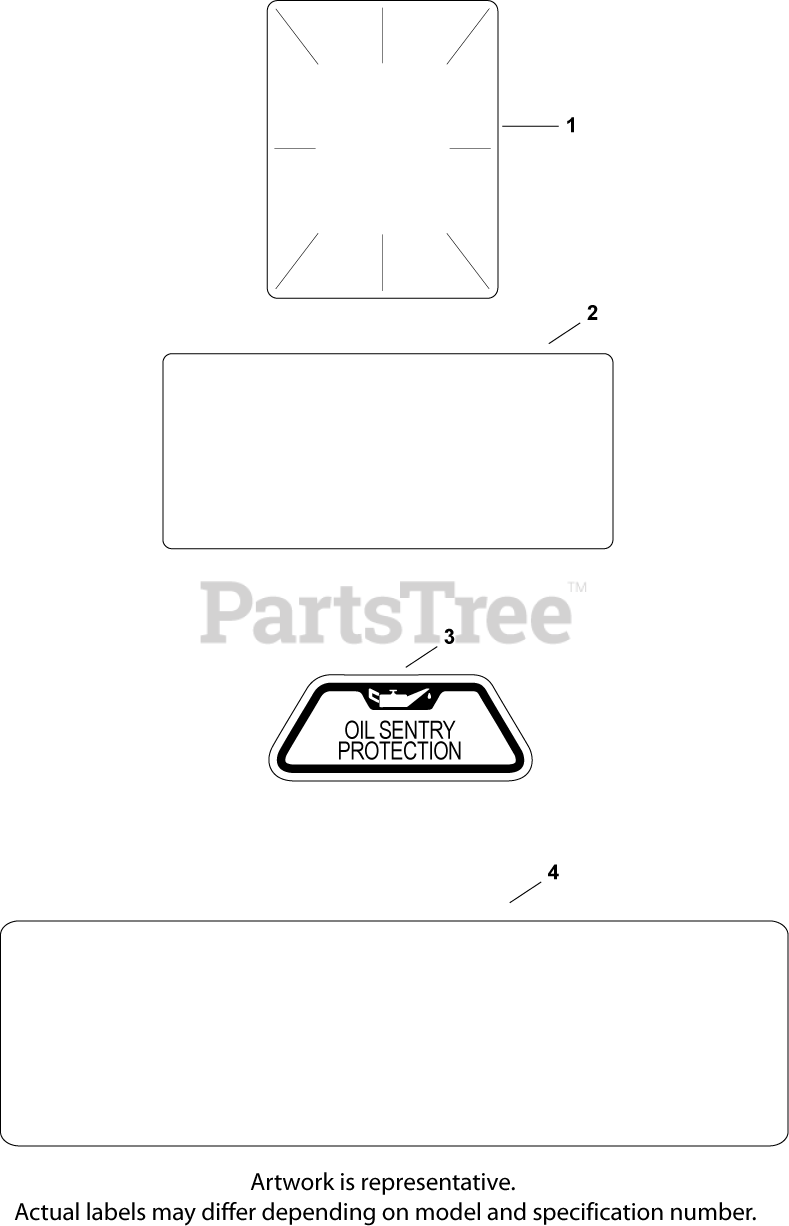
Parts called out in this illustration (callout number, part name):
1	DECAL, CLEAR LAMINATE USE 25 113 70-S
2	DECAL, REPL ENGINE(NONCERT)
3	DECAL, OIL SENTRY - (#DSC)
4	DECAL, 18 HP
